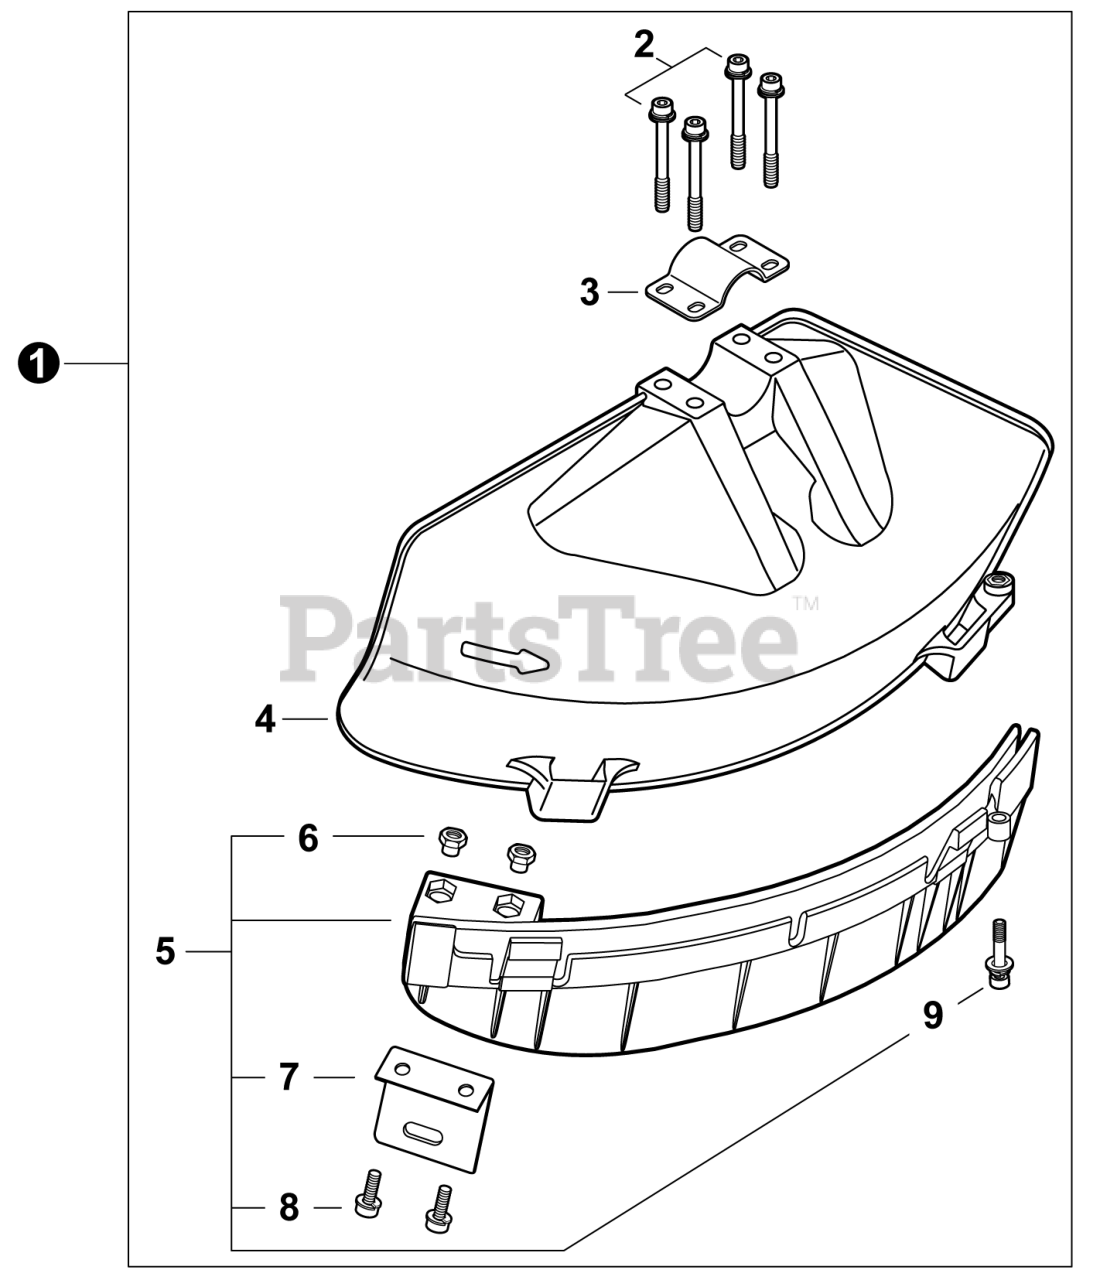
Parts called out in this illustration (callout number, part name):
1	SHIELD KIT, DEBRIS
2	BOLT M5x45
3	CLAMP, UPPER
4	SHIELD, DEBRIS - BLADE
5	EXTENSION ASSY, DEBRIS SHIELD
8	BOLT 5x16
9	BOLT M5x22
